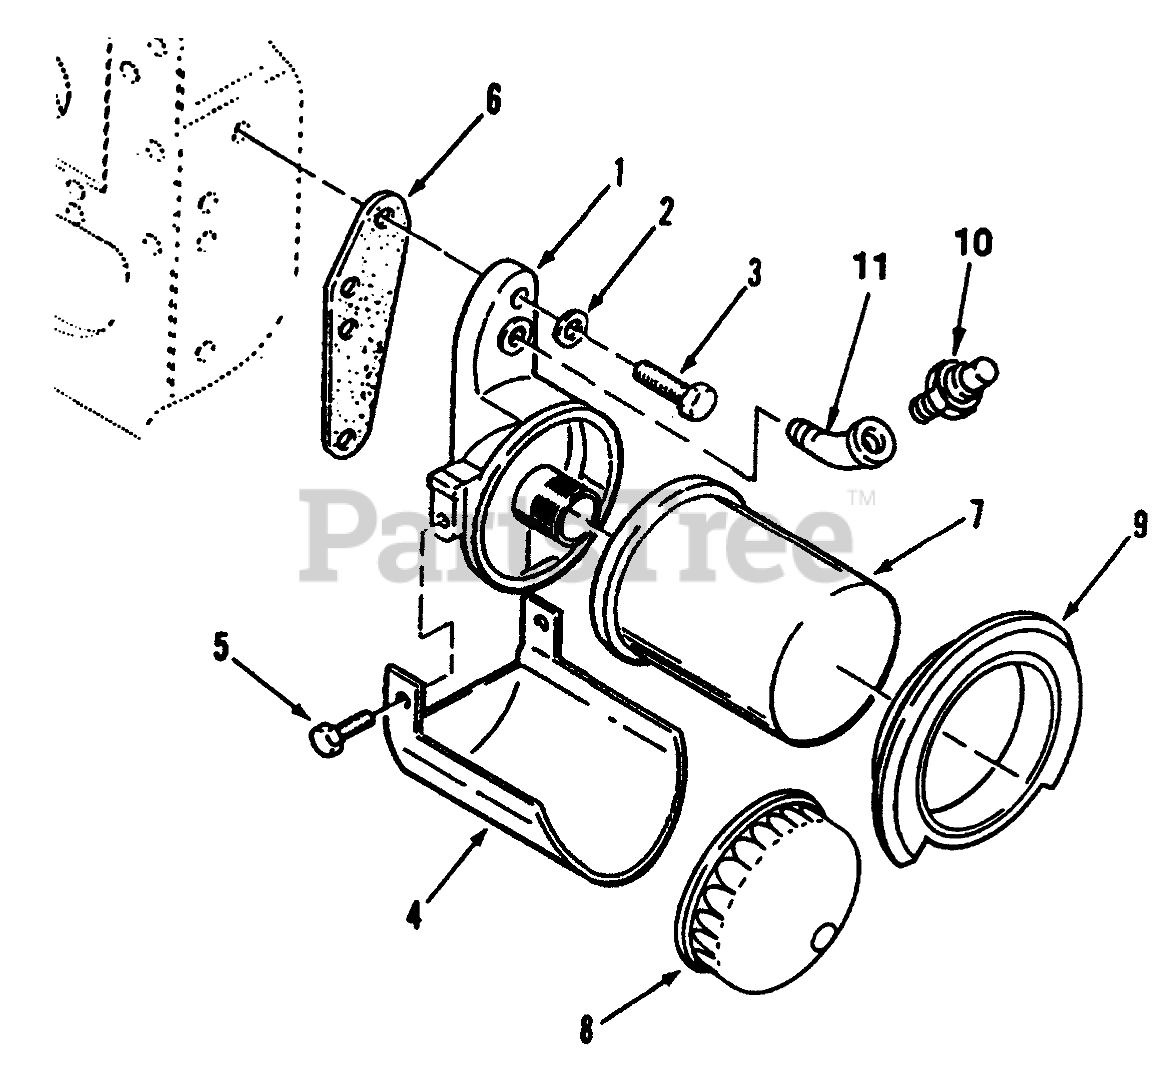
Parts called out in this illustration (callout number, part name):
1	ADAPTER-OIL FILTER
2	WASHER
3	HHCS 5/16-18 X 1
4	OIL-FILTER DRAIN
5	SCREW-HH
6	Gasket
7	OIL FILTER
8	WRENCH-OIL FILTER
9	GASKET - AIR SEAL
10	SWITCH - OIL PRESSURE
11	45 DEG STREET ELBOW
